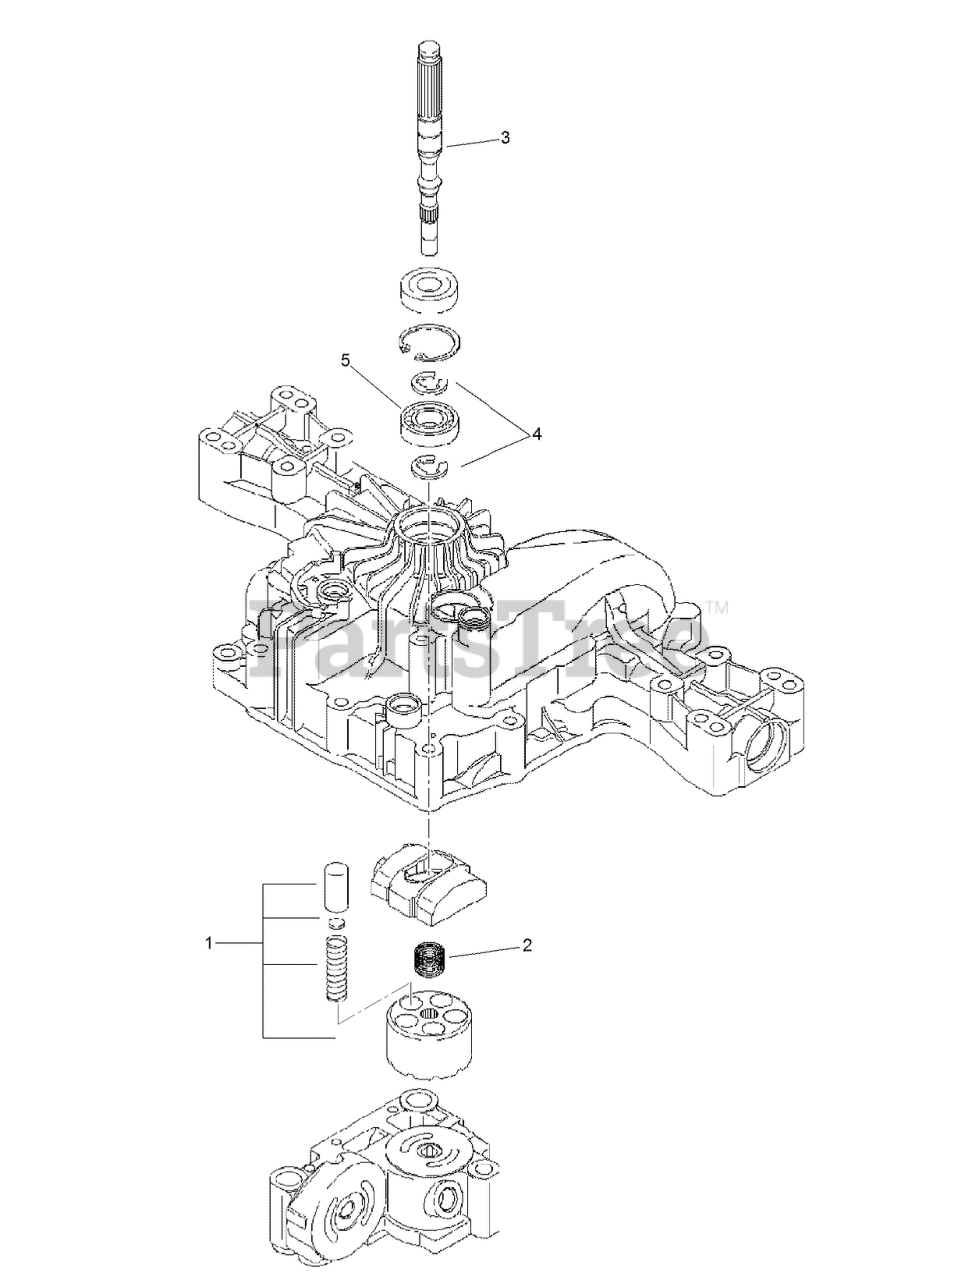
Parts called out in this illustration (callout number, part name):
1	Block-Cylinder
2	Spring-Pump
3	Shaft-Pump
4	E-RING
5	BEARING-BALL
